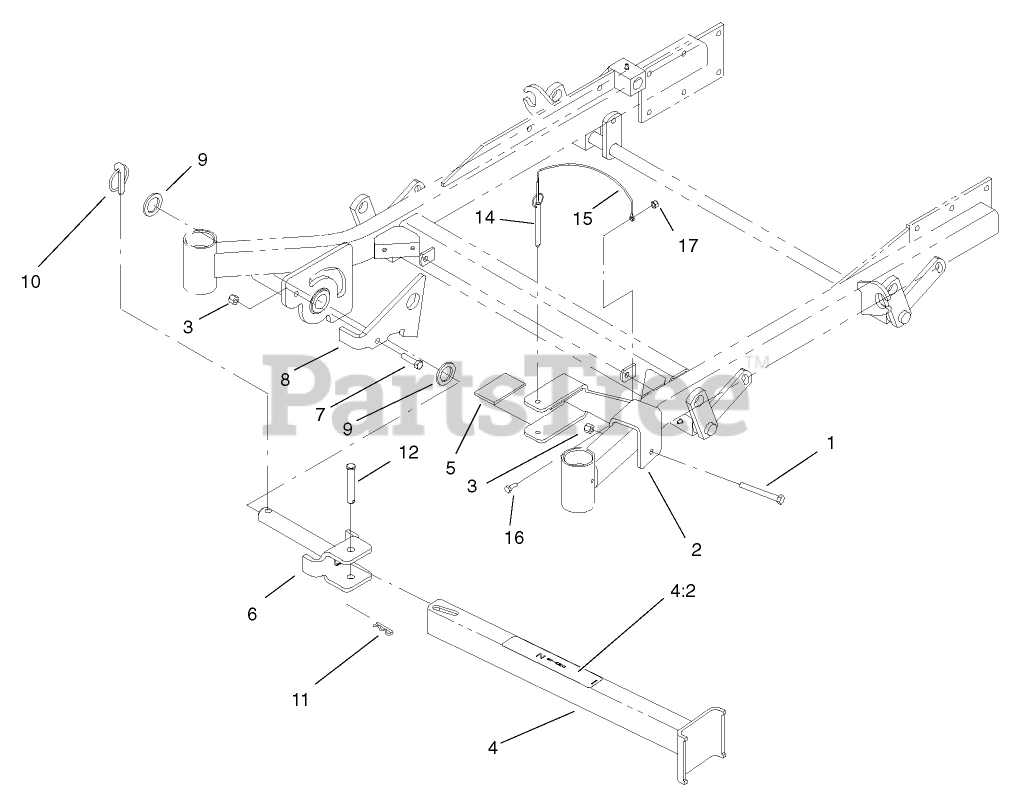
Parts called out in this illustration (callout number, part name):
1	SCREW-HH
2	BRACKET-CRADLE
3	NUT-LOCK, NI
4	Leg ASM
4:2	DECAL-Z STAND
5	PIN-CLEVIS
6	PIN-PIVOT
7	SCREW-HH
8	BRACKET-LATCH
9	WASHER-THRUST
10	PIN-LYNCH
11	PIN-HAIR
12	Cushion-Rubber
14	PIN-HITCH, COTTERLESS
15	LANYARD-NYLON
16	SCREW-HH
17	NUT-LOCK, NI
